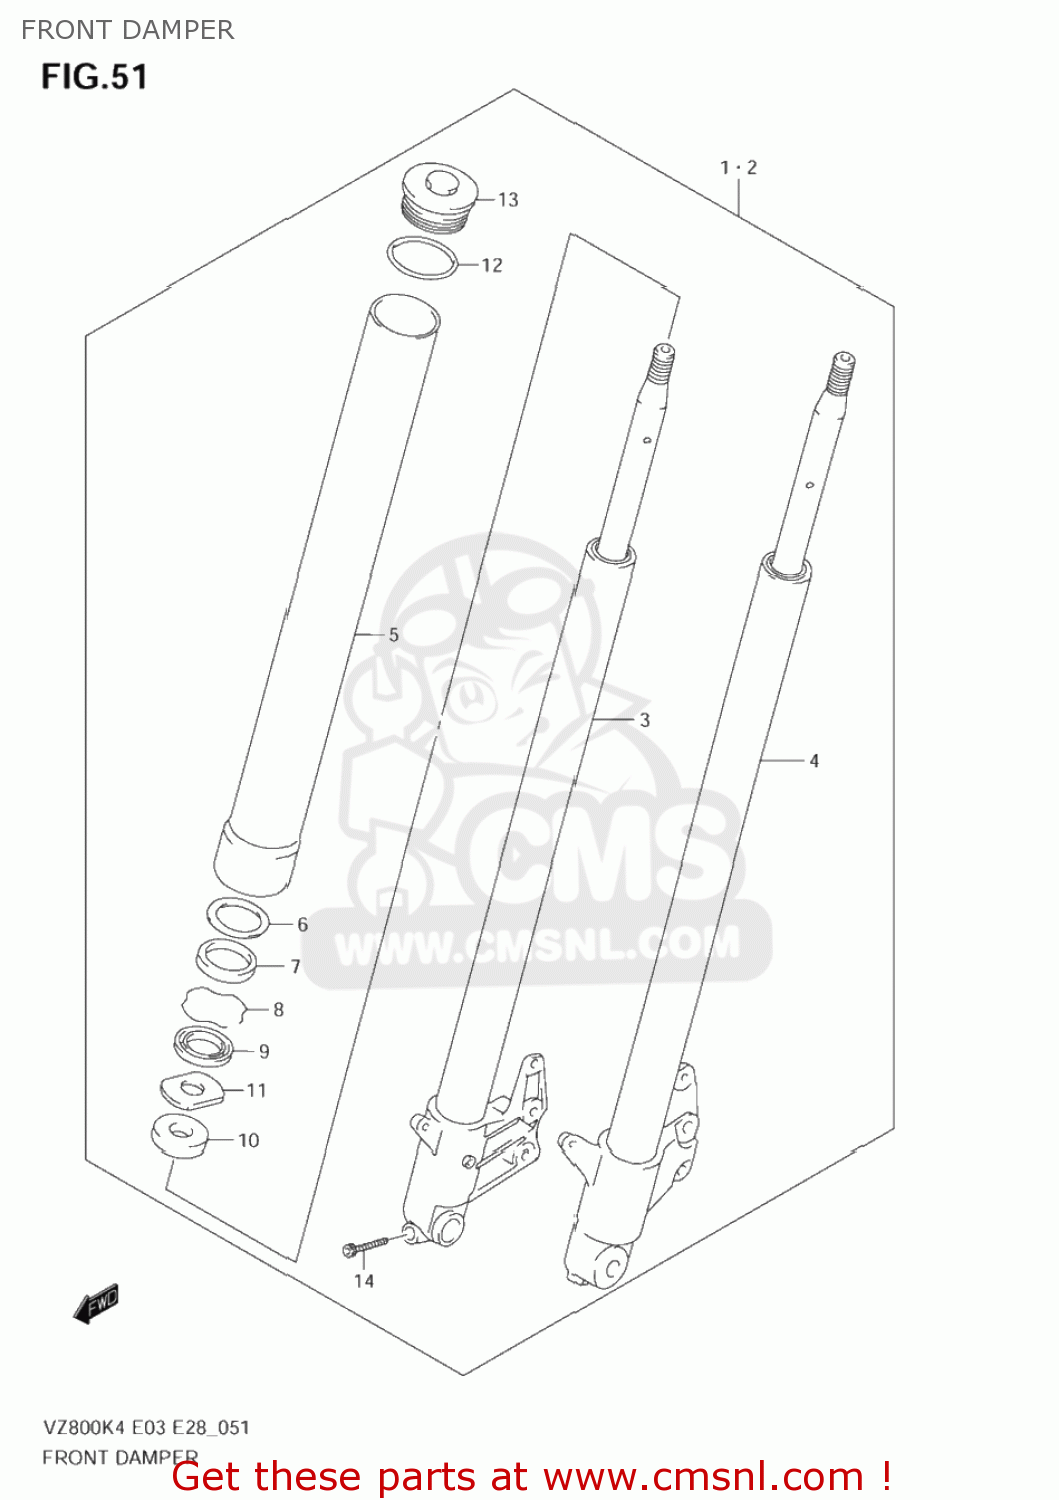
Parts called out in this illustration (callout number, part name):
1	DAMPER ASSY,FR FORK,R
2	DAMPER ASSY,FR FORK,L
3	DAMPER,FR FORK,R
4	DAMPER,FR FORK,L
5	TUBE,OUTER
6	WASHER,FORK OIL SEAL
7	SEAL,OIL
8	RING,OIL SEAL STOPPER
9	SEAL,DUST
10	RUBBER,CUSHION
11	NUT
12	O RING
13	CAP
14	BOLT,LWR
